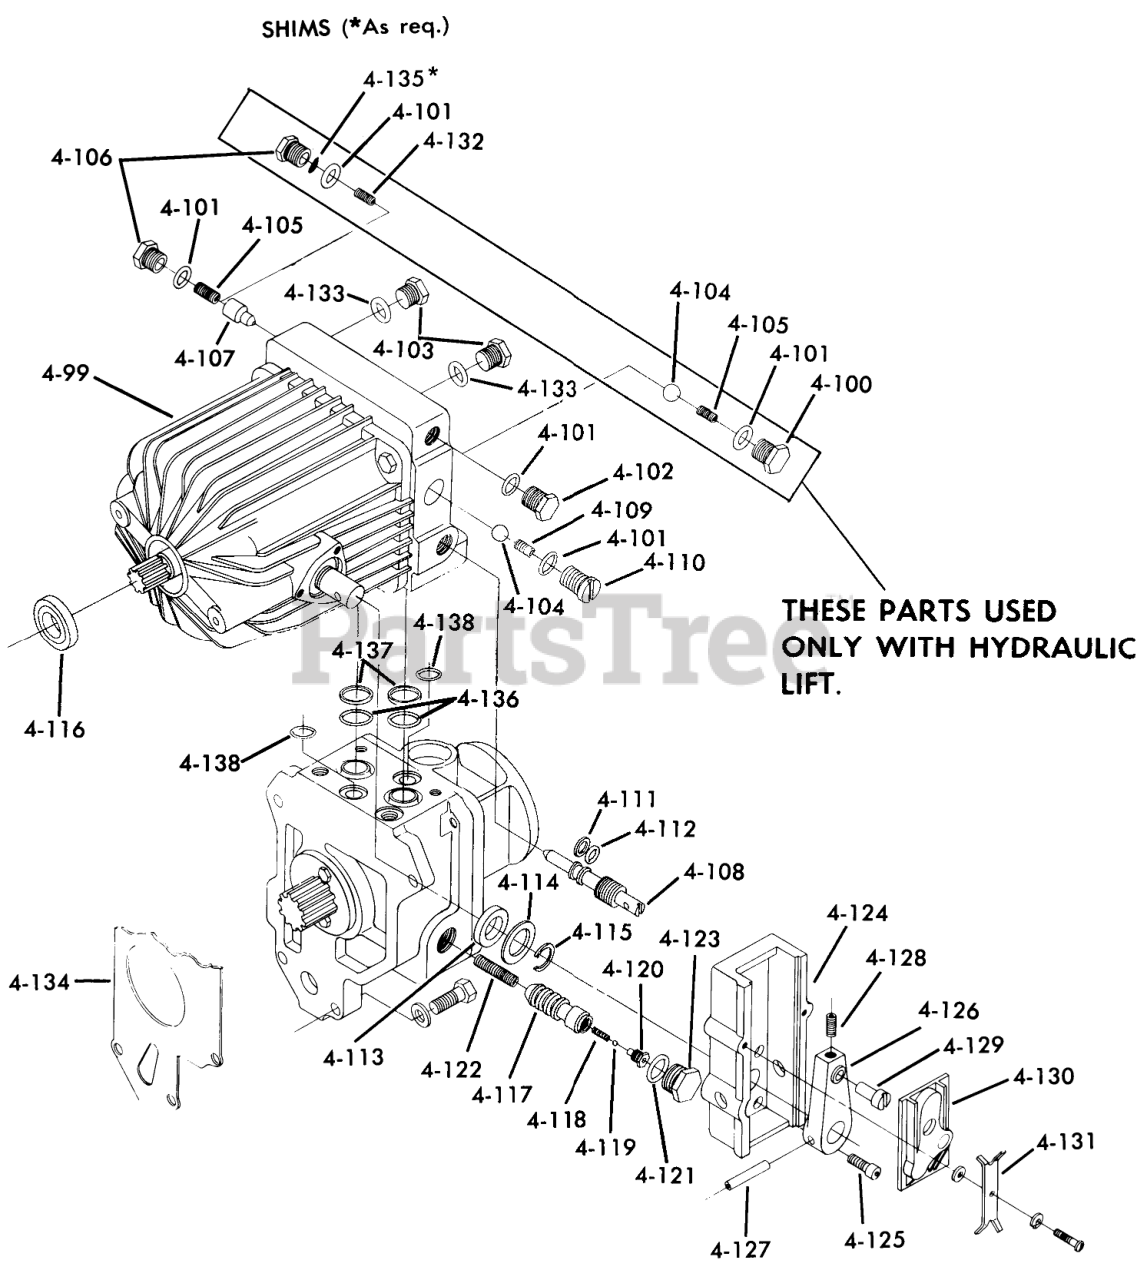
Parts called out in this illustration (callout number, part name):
4-99	Hydro Unit
4-100	Plug
4-101	O RING
4-103	Plug-Hex 9/16-18
4-105	Spring Chg. Rel. Valve
4-107	Cone
4-108	VALVE
4-109	Spring
4-110	PLUG
4-111	O-RING
4-112	Back Up Ring
4-113	SEAL
4-114	WASHER-LAMBERT
4-115	RING-LAMBERT
4-116	SEAL
4-117	Sleeve
4-118	SPRING
4-120	Valve
4-121	O-Ring
4-122	Spring
4-124	SUPPORT CAM BLOCK
4-125	SHCS 1/4-20 X 1/2
4-126	Belt Guide
4-127	PIN-ROLL 1/4 X 1 1/4
4-129	ECC CAM FOLLOWER
4-130	CAM
4-131	TENSION PLATE
4-131	SCREW
4-131	LOCKWASHER
4-131	WASHER
4-132	SPRING VALVE SUNSTR
4-133	0-Ring
4-134	GASKET
4-135	Shim Set
4-136	O RING
4-137	RING BACKUP
4-138	O RING
